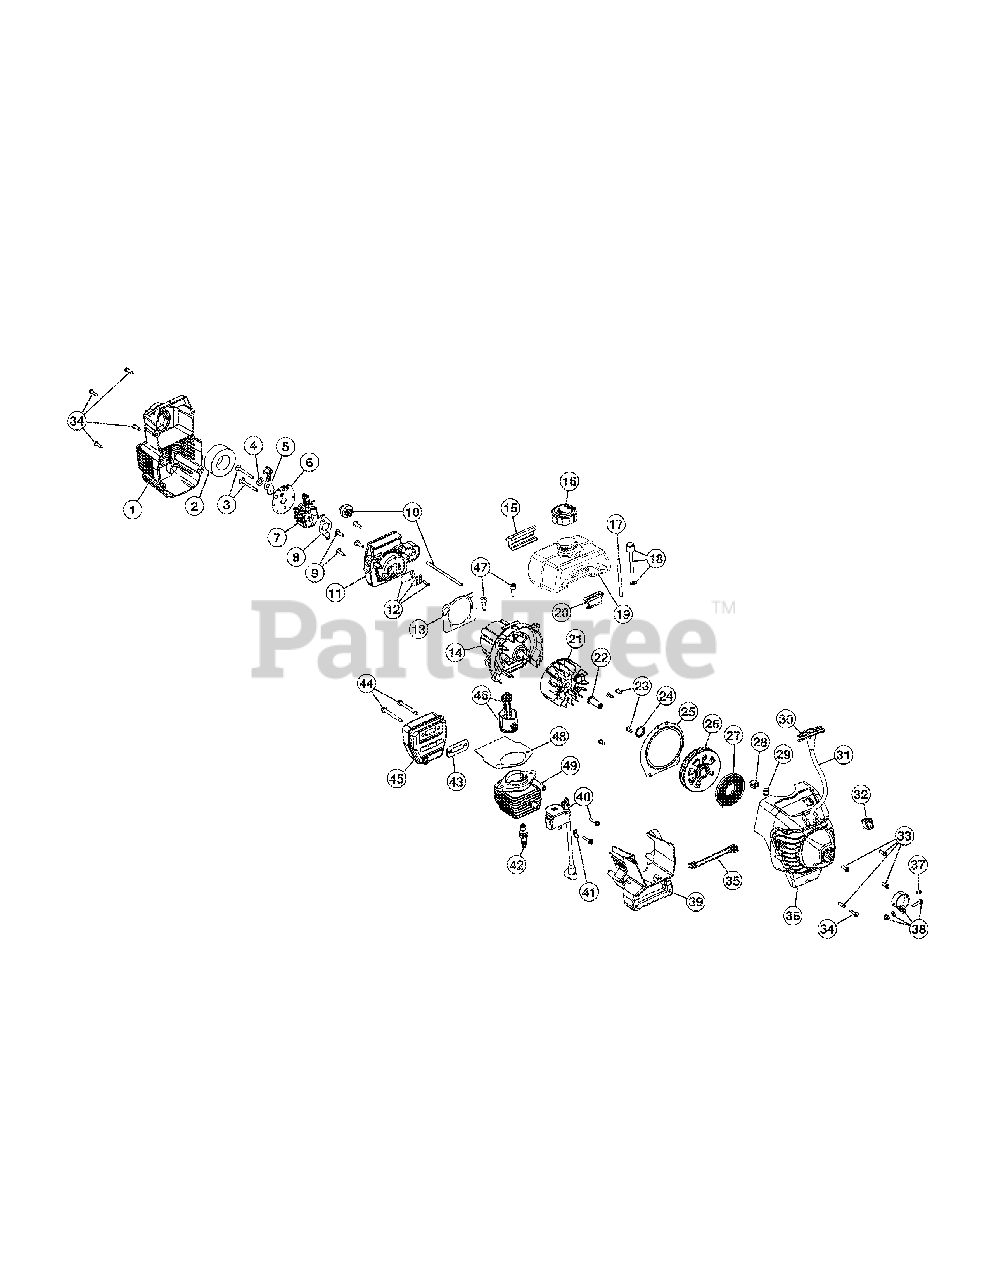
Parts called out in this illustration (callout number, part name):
1	Air Cleaner Cover Assembly (includes 2 & 34)
2	Air Cleaner Filter
3	Carburetor Mounting Screws
4	Wavey Washer
5	Choke Lever Assembly
6	Choke Lever & Plate (includes 5)
7	Carburetor Assembly (includes 8 & 18)
8	Carburetor Gasket
9	Carb Mount Screw
10	Primer and Hose Assembly
11	Carburetor Mount Assembly (includes 9, 12 & 13)
12	Reed Assembly
13	Carburetor Mount Gasket
14	Crankcase Service Assembly (includes 9)
15	Rear Mounting Pad
16	Fuel Cap Assembly
17	Fuel Return Line
18	Fuel Line Assembly
19	Fuel Tank Assembly (includes 16-18)
20	Front Mounting Pad
21	Flywheel Assembly
22	Square Nut Drive
23	Plate Screw
24	Palnut
25	Pressure Plate (includes 23 & 28)
26	Recoil Pulley Assembly (includes 24)
27	Recoil Spring
28	Eyelet Retainer
29	Rope Guide
30	Pull Handle
32	Switch Assembly
33	Housing Screw
34	Cover Screw
35	Wire Lead
36	Starter Housing Assembly (includes 23-35)
37	Anti-Rotation Screw
38	Clamp Assembly (includes 37)
39	Shroud Extension and Stand (includes 34)
40	Module Assembly
41	Ground Tab
42	Spark Plug
43	Exhaust Gasket
44	Muffler Mounting Bolt Assembly
45	Muffler Assembly (includes 43, 44 & Spark Arrestor)
46	Piston & Rod Assembly
47	Cylinder Bolt
48	Cylinder Gasket
49	Cylinder Assembly (includes 47 & 48)
